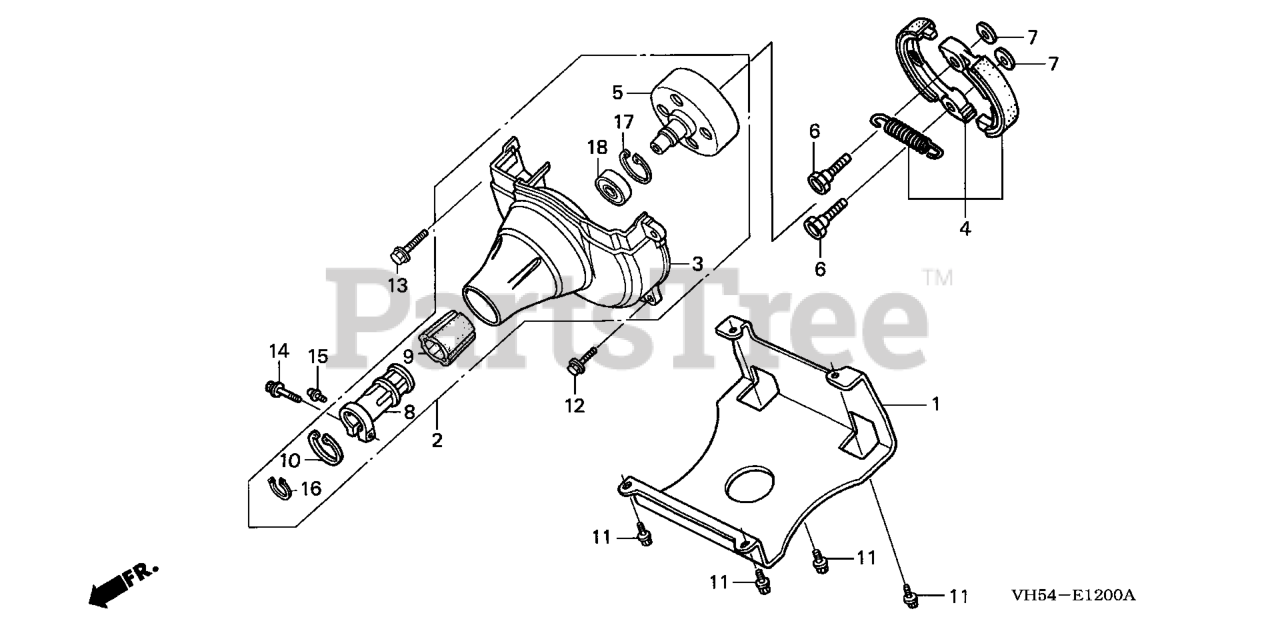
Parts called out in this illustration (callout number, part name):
1	GUARD, TANK
2	COVER ASSY., FAN *NH35M* (CLOUD SILVER METALLIC)
3	COVER, FAN *NH35M* (CLOUD SILVER METALLIC)
4	CLUTCH ASSY.
5	CLUTCH (OUTER)
6	BOLT, CLUTCH (8MM)
7	WASHER, CLUTCH (8X17)
8	BRACKET, ENGINE MOUNTING
9	RUBBER, ENGINE MOUNTING
10	CIRCLIP (INNER) (45MM)
11	BOLT, FLANGE (5X12)
12	BOLT, FLANGE (5X18)
13	BOLT, FLANGE (5X22)
14	BOLT-WASHER (6X28)
15	SCREW-WASHER (5X10)
16	CIRCLIP (OUTER) (15MM)
17	CIRCLIP (INNER) (35MM)
18	BEARING, RADIAL BALL (6202)
